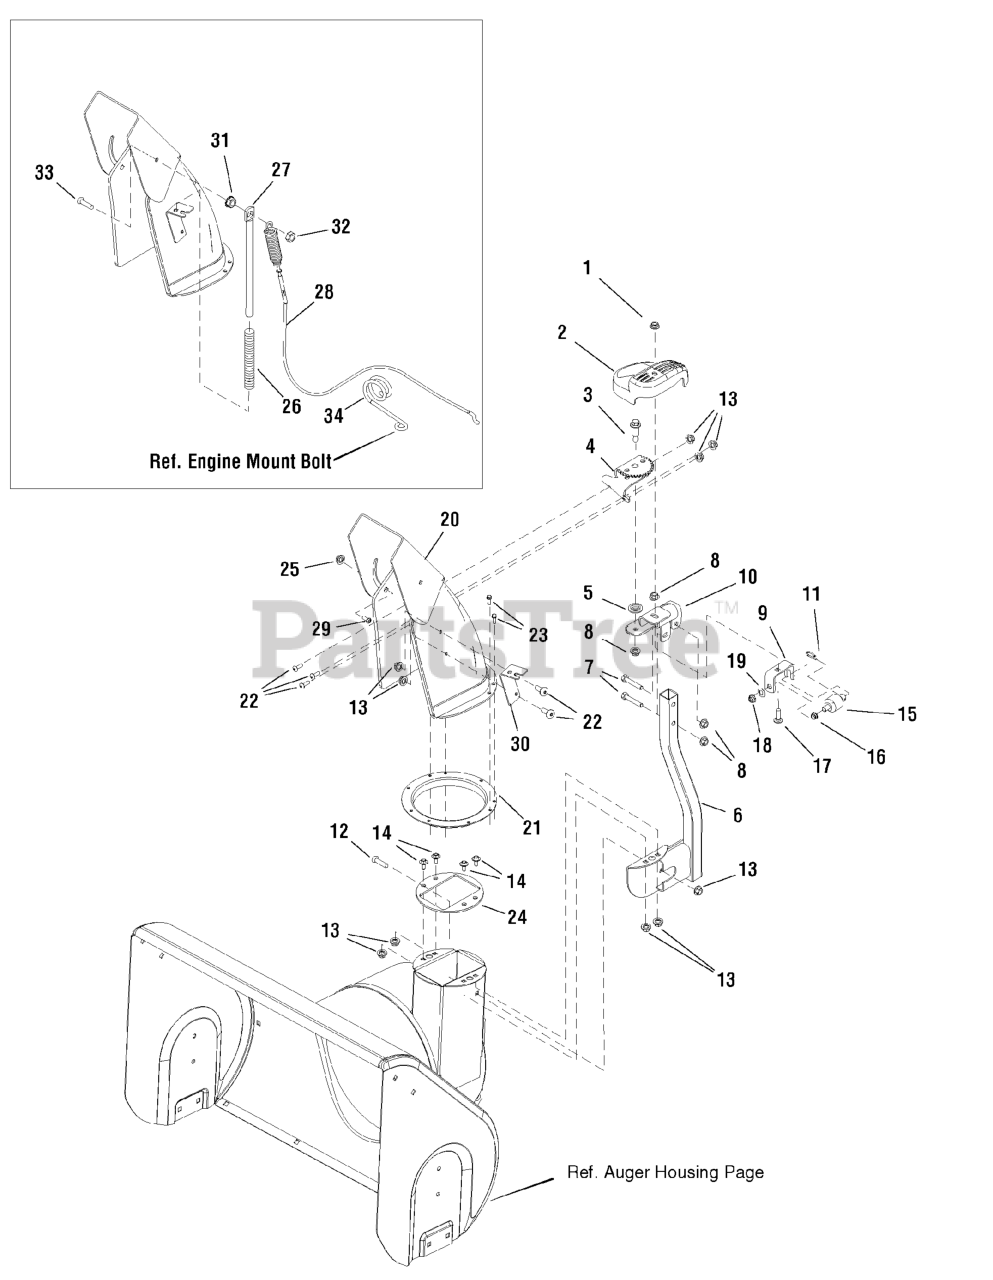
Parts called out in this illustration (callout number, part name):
1	NUT, Hex Flange 5/16-18 Two Way Lock
2	COVER, Gears
3	BOLT, Shoulder 5/16-18 G5
4	GEAR & SUPPORT ASSEMBLY, Chute
5	WASHER, Powdered Metal
6	CHUTE SUPPORT ASSEMBLY
7	SCREW, Hex Head Cap, 5/16-18 x 1 3/4
8	NUT, Hex KEPS 5/16-18 Conical Washer
9	SUPPORT, Worm "U" 10GA
10	SUPPORT, Gear & Chute 10GA
11	PIN, Hair Chute Gear
12	BOLT, CARRIAGE 0.25-20 x 0.75
13	NUT, Nylock Flanged, 1/4-20
14	SCREW, HEX WASHER
15	WORM, Chute L.H.
17	BOLT, 5/16-18 X 1.00
18	NUT, Hex Lock Jam ESNA Lite 3/8-24
19	WASHER, Cup
20	DISCHARGE CHUTE ASSEMBLY
21	CHUTE RING
22	SCREW, Truss Head, 1/4-20 x 3/4
23	CAPSCREW, Hex Head Taptite, 1/4-20 x 1/2
24	GUIDE, CHUTE RING
25	NUT-HEX FLANGE.312-18 ESNA
26	SPRING, Compression
27	ROD, Spring
28	CABLE DEFLECTOR
29	SCREW, Torx Truss Head, 5/16-18 x 7/8, Black
30	BRACKET, CABLE DEFLECTOR
31	NUT, Hex KEPS, 5/16-18
32	JAM NUT, Top Lock, 5/16-18
33	SCREW, BUTTON HEAD, 5/8-18 x 1.25
34	WIRE FORM, REMOTE CHUTE CABLE
